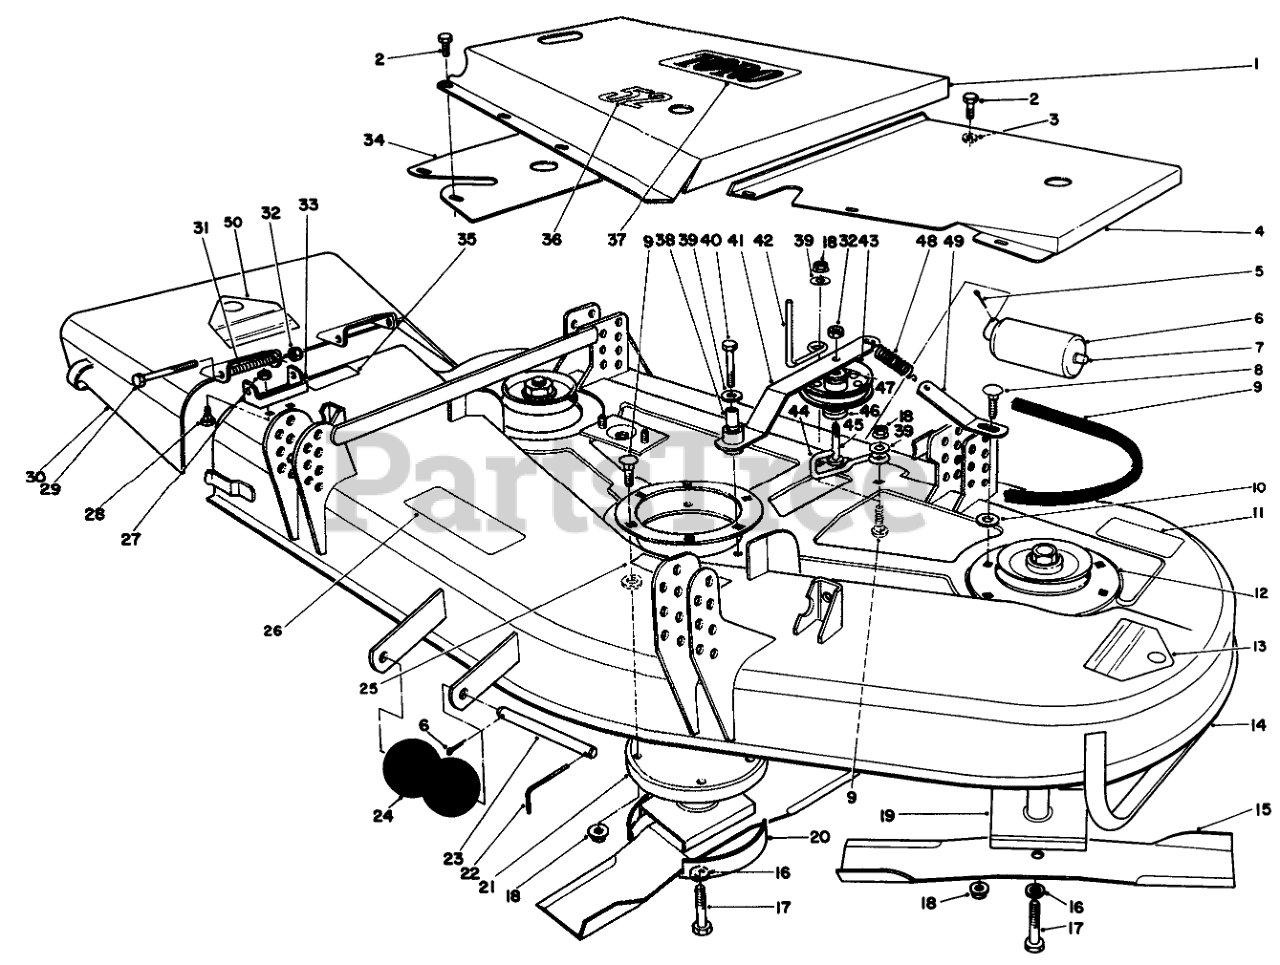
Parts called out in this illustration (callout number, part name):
1	CENTER COVER WA 52 R
2	SCREW-HHFTF
3	WASHER-FLAT
4	Cover
5	PIN-COTTER
6	ROLLER-DECK
7	SHAFT-ROLLER, REAR
8	SCREW-CARR
9	V-BELT
10	WASHER-FLAT
11	DECAL-TORQUE
12	SUPPORT-DECK, RING
13	DECAL-DANGER
14	Deck Assembly (Incl. Ref. #11, 13, 25 & 26)
15	Blade
16	WASHER-LOCK
17	SCREW-BLADE
18	NUT-HF
19	SPINDLE ASM
20	Cup-Scalp
21	HOUSING - SPINDLE ASM
22	PIN-SPECIAL
23	SHAFT-ROLLER
24	ROLLER
25	DECAL-DANGER
26	DECAL-DANGER, THROWN OBJECT
27	NUT-LOCK, CONE
28	SCREW-CARR
29	SCREW-HH
30	Deflector-Grass (Incl. Ref. #50)
31	SPRING
32	NUT-HEX
33	Bracket-Pivot
34	Cover
35	DECAL-DANGER
36	DECAL
37	DECAL
38	SLEEVE
39	WASHER-FLAT
40	SCREW-HH
41	Arm-Idler
42	ROD-BELT
43	PULLEY-IDLER
44	GUIDE-BELT
45	Bolt-Special
46	BUSHING-PULLEY
47	WASHER-FLAT
48	SPRING-EXTENSION
49	PLATE-SPRING
50	DECAL-DANGER
